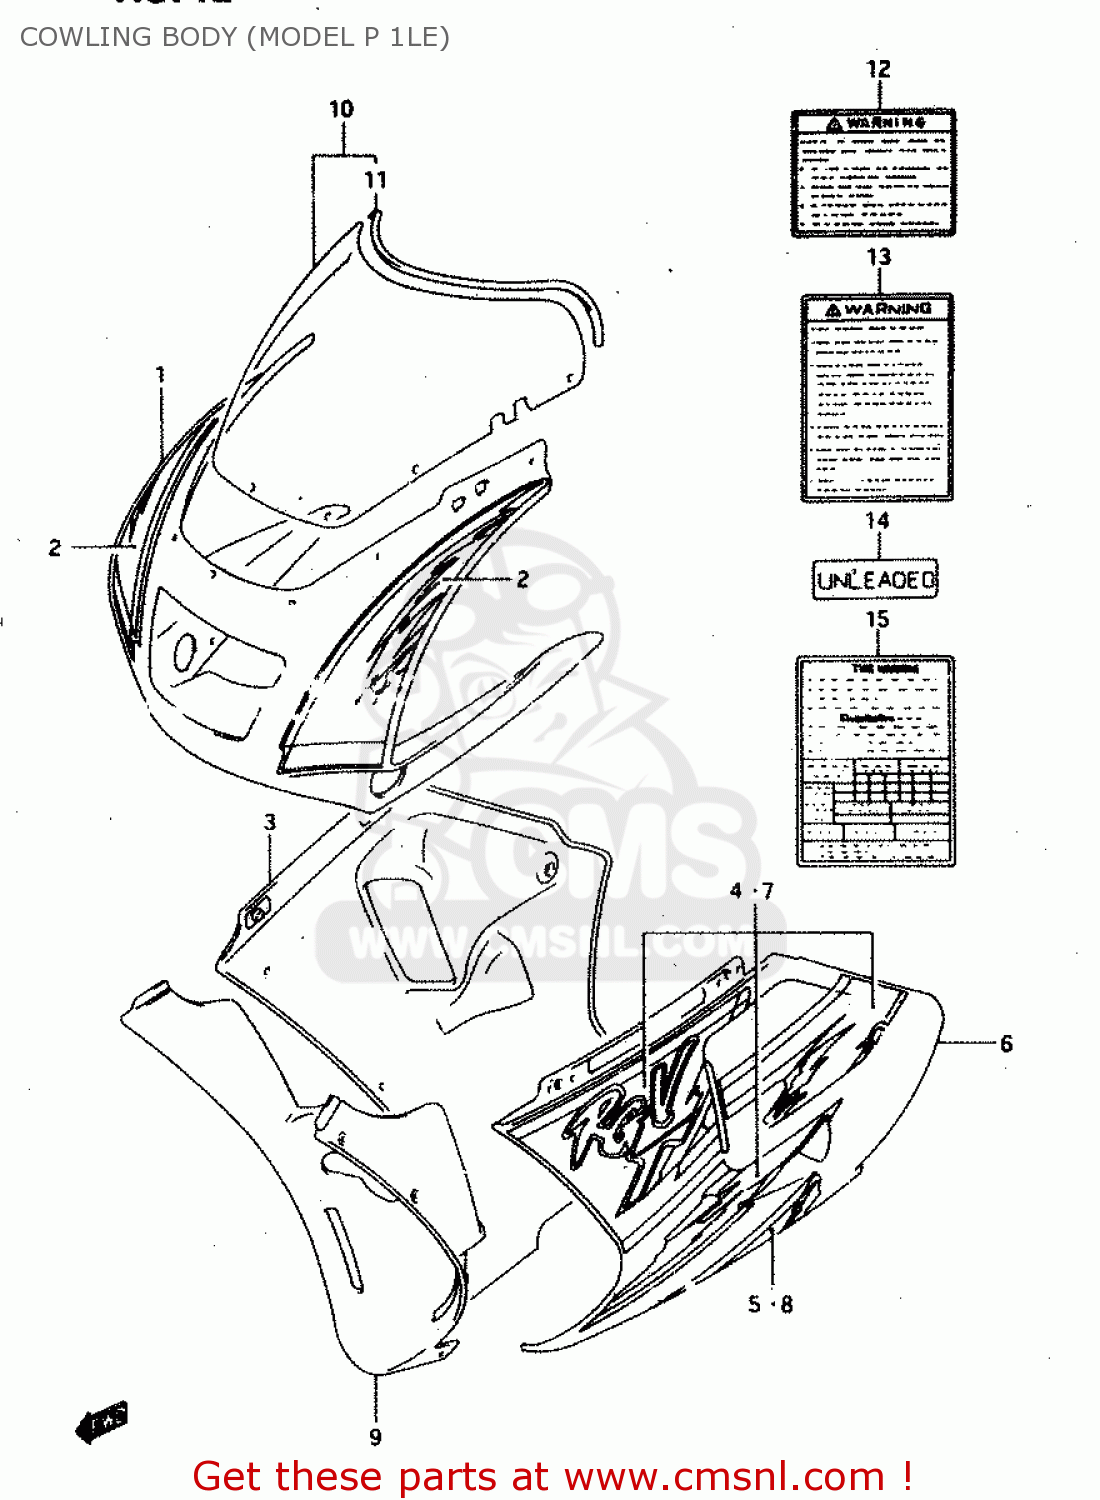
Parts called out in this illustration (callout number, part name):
1	COWLING ASSY,B
2	TAPE SET,COWL BODY
3	COWLING ASSY,UNDER,R
4	TAPE SET, UNDER RH
5	TAPE,COWL UNDER,R
6	COWLING,UNDER,
7	TAPE SET,CWL.L
8	TAPE,COWL UNDER,L
9	COWLING,UNDER CTR
10	SCREEN SET,WIND
11	MOLDING WINDSCREEN
12	LABEL
13	LABEL (WARNING SCREEN)
14	LABEL,CAUTION
15	LABEL, TIRE AIR PRESSURE
